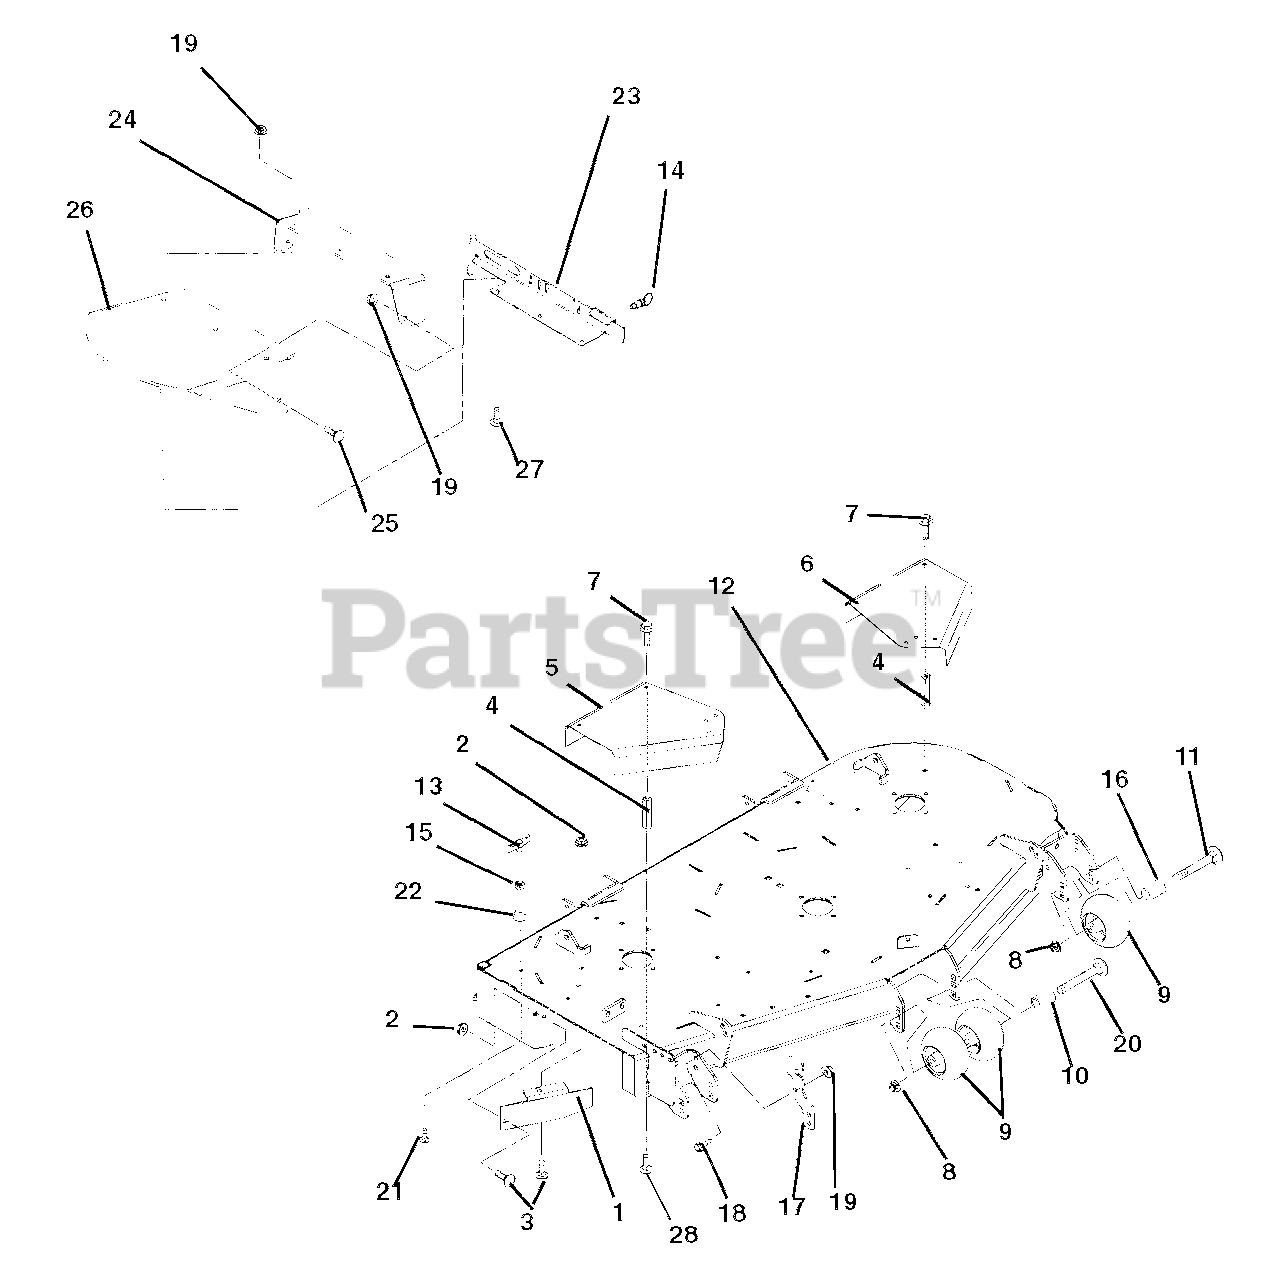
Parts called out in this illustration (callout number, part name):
1	60-in. Discharge Baffle (182)
2	Nut, .31-18 Nyloc Flange
3	Bolt, Round Head Square Neck .31-18 x 1.00 Grade 5
4	Nut, Coupling .31-18 x 3.00
5	60-in. Right Hand Spindle Guard (182)
6	60-in. Left Hand Spindle Guard (182)
7	Bolt, SEMS .31-18 x .62
8	Nut .50-13 Nyloc Flange
9	Anti-Scalp Wheel
11	Bolt-Round Head Square Neck .50-13X5.00
12	60-in. Mower Deck (182)
13	Knob, Wing .312-18
14	Pin, Plunger Pull .50-13 Thread x .310 Diameter
15	Nut, Locking, Center .31-18
16	Spacer, .510 x .625 x 3.35
17	Chute, Storage Bracket
18	Bolt, Hex .38-16 x 1.00
19	Nut, .38-16 Nyloc Flange
20	Bolt, Round Head Square Neck .50-13 x 8.50
21	Bolt, Round Head Square Neck .31-18 x 1.50
22	Bumper, Recessed 1.50 x .63 , .31 Thru Hole
23	52-inch and 60-inch Discharge Chute Mounting Weldment
24	Rubber Discharge Chute Support
25	Bolt, Round Head Square Neck .38-16 x 1.00 Grade 5
26	Chute, Rubber Discharge
27	Bolt, Round Head Square Neck .38-16 x 1.25 Grade 5
28	Bolt, Round Head Square Neck .31-18 x .75
